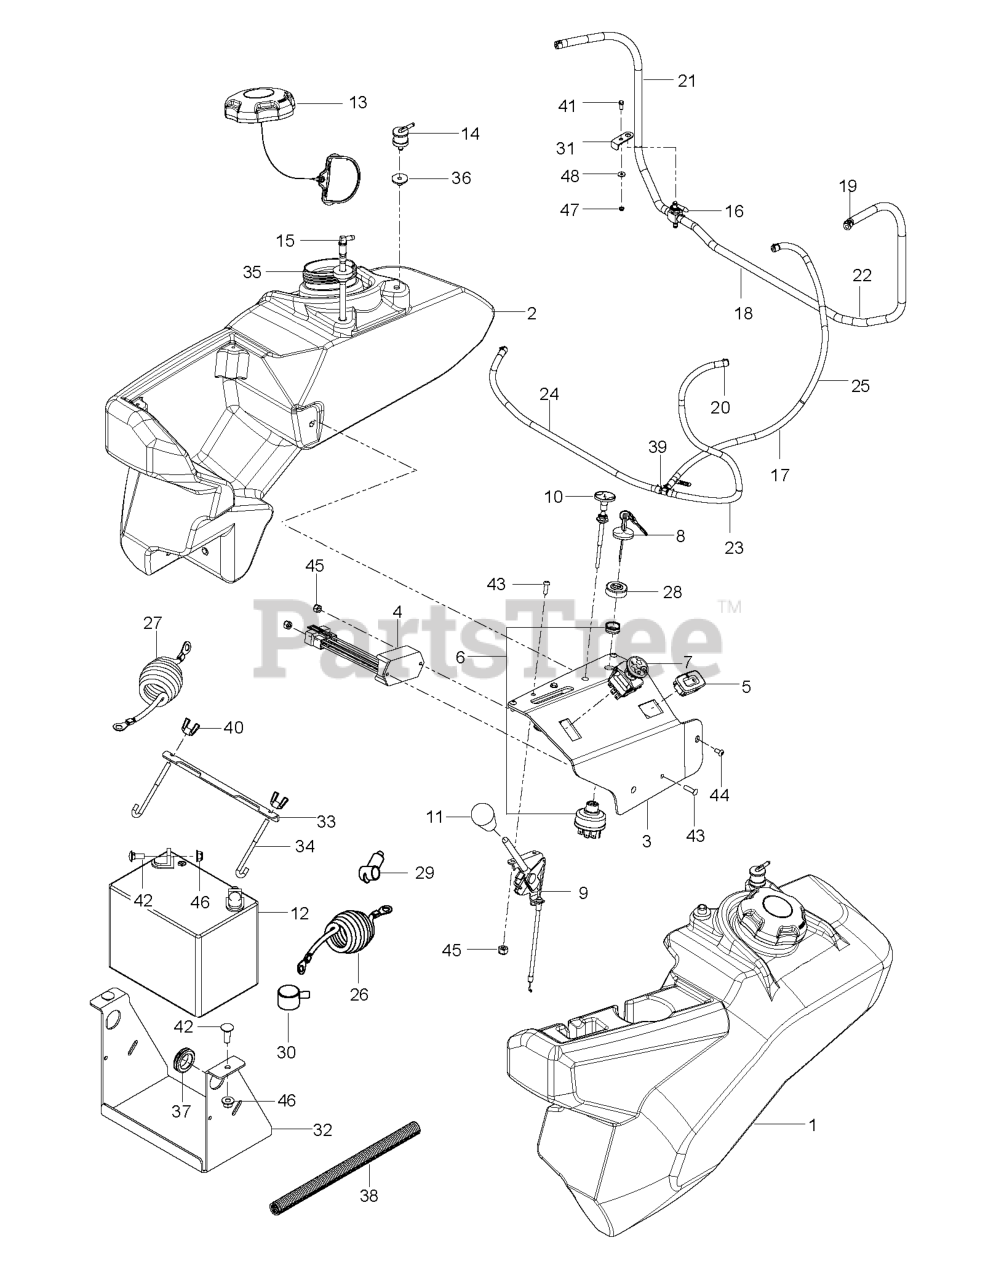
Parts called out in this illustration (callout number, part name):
1	FUEL.TANK.ASM.LH.PZ.BLACK.17
2	FUEL.TANK.ASM.PZ.RH BLACK.17
3	PANEL, CONTROL GAS BLACK
4	TIMER, SEAT
5	GUAGE.SRVCMNDR.HRMTR.
6	SWITCH, IGNITION, INDAK
7	RP SWITCH.PTO.TERMINAL.STD.RED
8	KEY, IGNITION
9	CABLE, THROTTLE, 46"
10	CABLE, CHOKE, 48"
11	KNOB - SHIFT
12	BATTERY, 12 V 330 AMP
13	CAP, FUEL
14	VALVE.FUEL.CHECK
15	FITTING, FUEL
16	FUEL VALVE
17	HOSE.ASM.VAPOR.LINE.21-30-39
18	ASSEMBLY, FUEL LINE
19	HOSE CLAMP
20	CLAMP, HOSE
21	HOSE.1/4".LOW.PERM.FUEL.LN.22"
22	HOSE.1/4".LOW.PERM.FUEL.LN.38"
23	HOSE.3/16".VAPOR.LINE.39"LGTH
24	HOSE.3/16".VAPOR.LINE.21"LGTH
25	HOSE.3/16".VAPOR.LINE.30"LGTH
26	CABLE, POSITIVE, 55"
27	CABLE, NEG, 55"
28	CAP IGNITION NUT
29	INSULATOR
30	LOOM SPLIT 5/8, 32"
31	BRACKET.VALVE.PNT.BLACK.X431
32	BRACKET, BATTERY, BLK
33	BRACKET.BATTERY.MOUNT.PLATED
34	HOOK, "J"
35	RUBBER GROMMET
36	GROMMET, CHECK VALVE
37	RUBBER GROMMET
38	LOOM SPLIT 5/8, 32"
39	TEE, FUEL LINE 3/16"
40	WING NUT 1/4
41	HCS 1/4C X 3/4 HCS
42	BOLT 5/16-18 X3/4 ZN/YEL GR 5
43	SCR #10-24 X .75 SKT HD BLK
44	SCR #10-24 X 3/8 SKT HD BLK OX
45	NUT 10-24 NYLOC
46	5/16-18 NYLOC FLANGE NUT
47	JAM NUT 1/4C (2 2 PW01)
48	WASHER 1/4 FLAT
